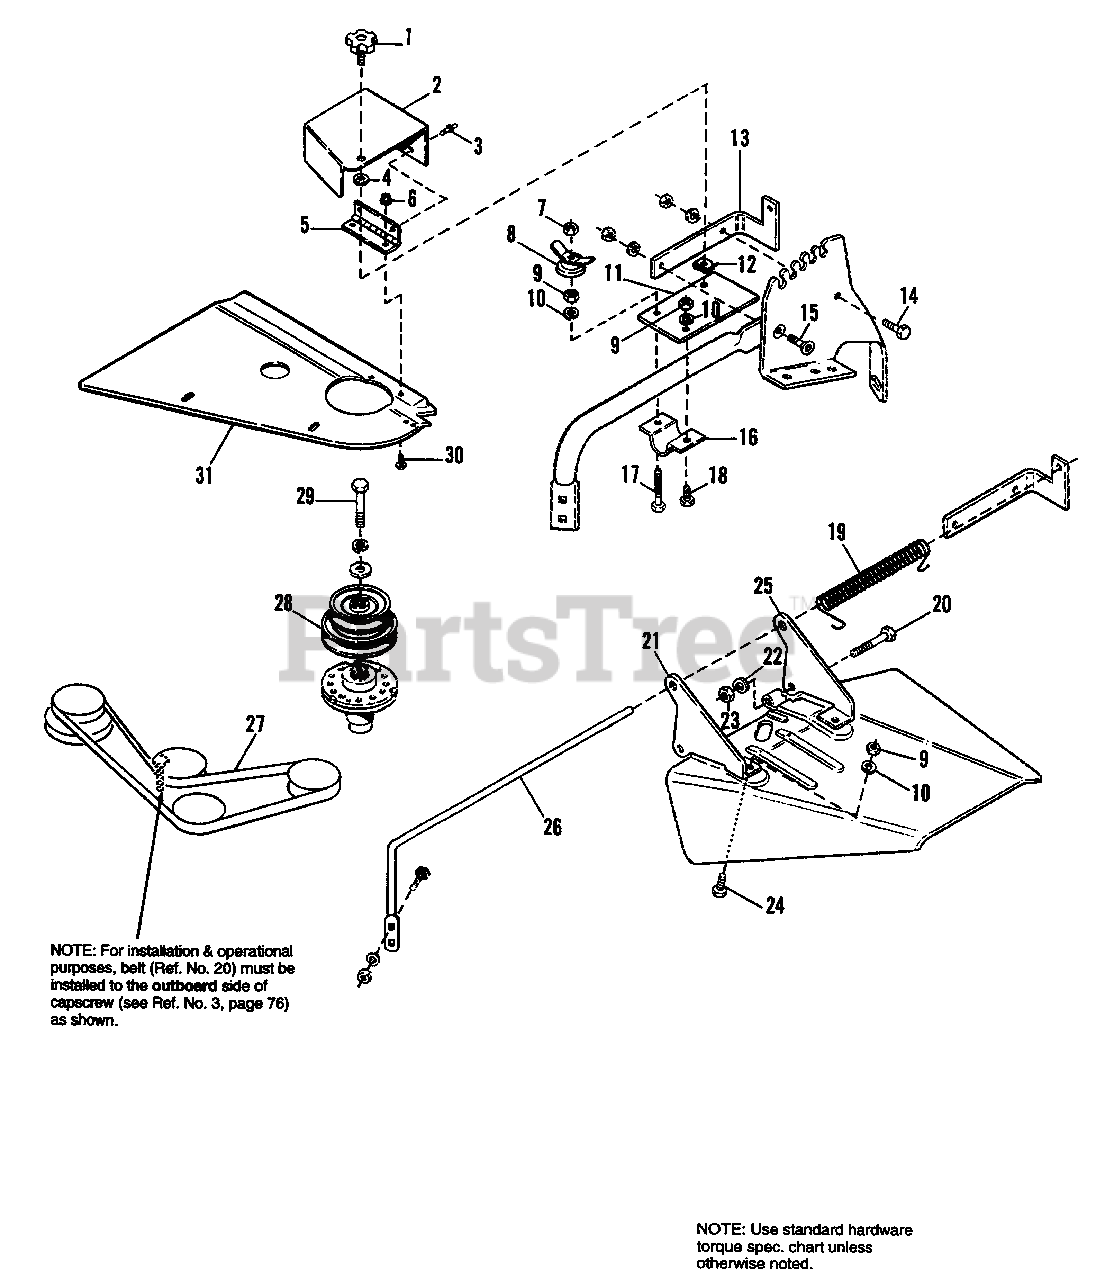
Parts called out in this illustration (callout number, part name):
1	PLASTIC KNOB
2	COVER ASSY.
3	RIVET
4	PUSH NUT, 5/16
6	NUT, Hex Washer, #10-32
7	NUT, Hex Full Lock, 5/16-18
8	WING NUT ASSY.
9	NUT, Hex Full, 5/16-18
10	LOCKWASHER, 5/16
11	CLAMP, Upper
12	PAL NUT, 5/16-18
13	PIVOT ASSY., Deflector
14	CAPSCREW, Hex, 5/16-18 x 1-1/4
15	SCREW, Flat Hd., Hex Soc., 5/16-18
16	CLAMP, Lower
17	CAPSCREW, Hex Hd., 5/16-18 x 2-1/2
18	CAPSCREW, Hex Hd., 5/16-18 x 5/8
19	SPRING, Torsion
20	CAPSCREW, Hex Hd., 7/16-14 x 2-1/4
20	CAPSCREW, Hex Hd., 7/16-14 x 2-3/4
21	PIVOT, Bracket, L.H.
22	LOCKWASHER, 7/16
23	NUT, Hex, Full, 7/16-14
24	CAPSCREW, Hex, 5/16-18 x 7/8
25	PIVOT, Bracket, R.H.
27	V-BELT
28	PULLEY ASSY.
29	CAPSCREW, Hex Hd., 7/16-14 x 2-1/4
30	SCREW, Rd. Hd., Mach., #10-32 x 3/8
31	COVER, L.H., Mower
